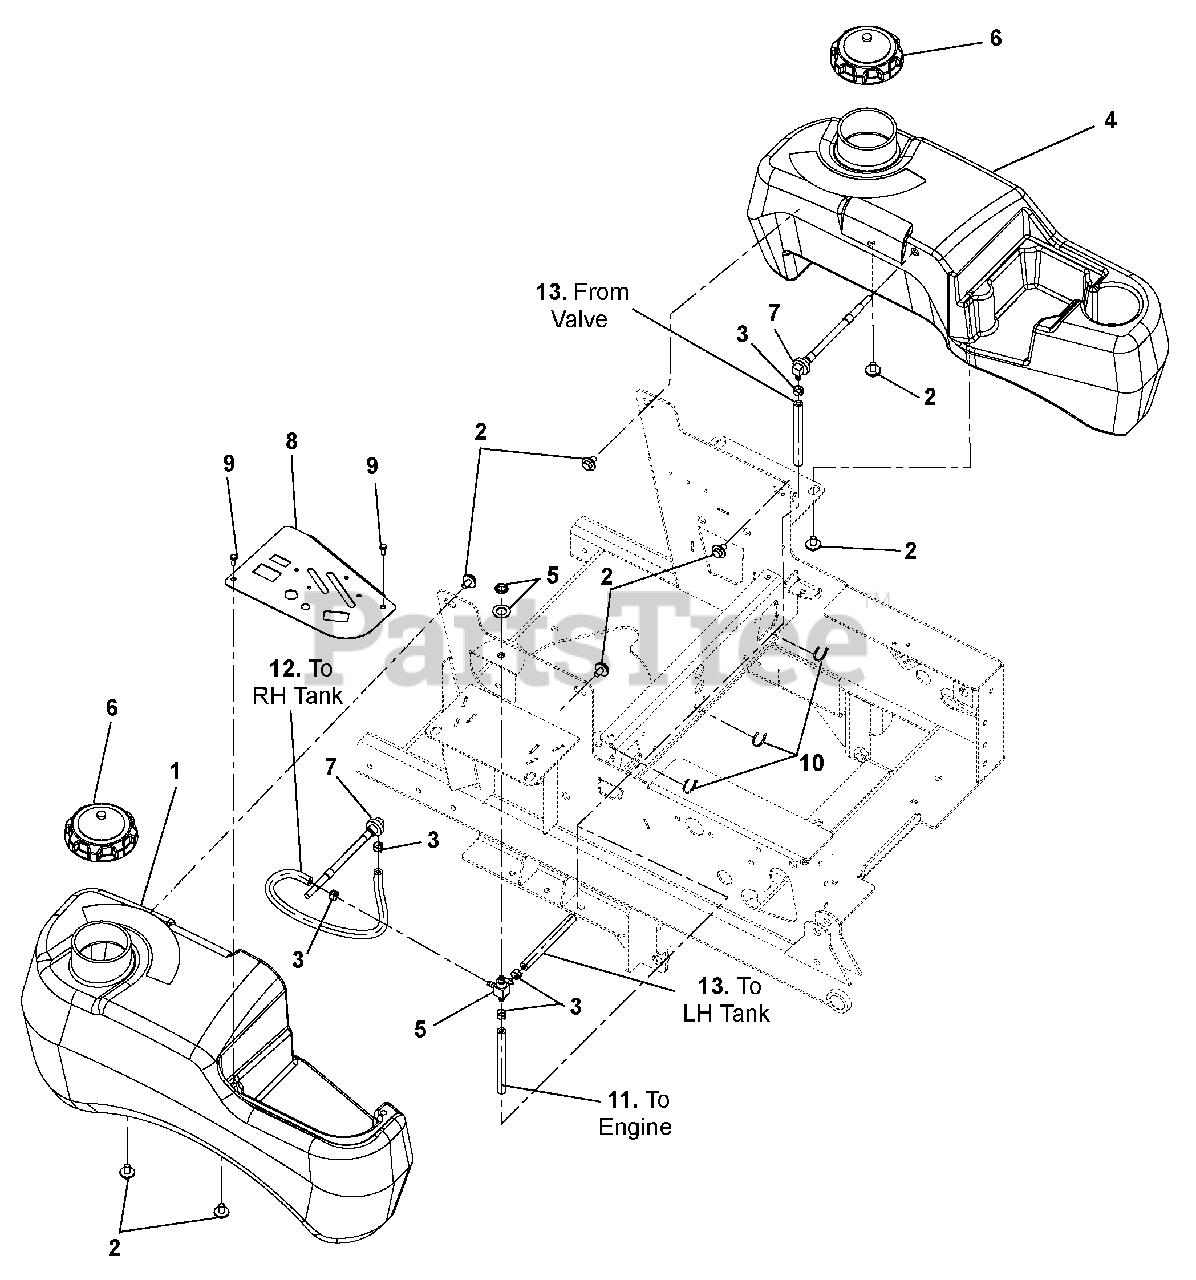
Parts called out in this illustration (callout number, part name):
1	TANK, GAS RH (100 SERIES)
2	BOLT, SEMS .31-18 X .62
3	CLAMP, FUEL LINE
4	TANK, LH FUEL 100 S. W/O HOSE
5	VALVE, FUEL
6	CAP - FUEL
7	ASS'Y,MEDIUM TANK FUEL PICK-UP
8	PANEL, CONTROL IZ - BLACK
9	SCR-MCH 10-24X.50 HWHSTAINLESS
10	CABLE TIE LG 5-1/2
11	HOSE, .25 LOW-PERM BULK GAS
12	HOSE, .25 LOW-PERM BULK GAS
13	HOSE, .25 LOW-PERM BULK GAS
